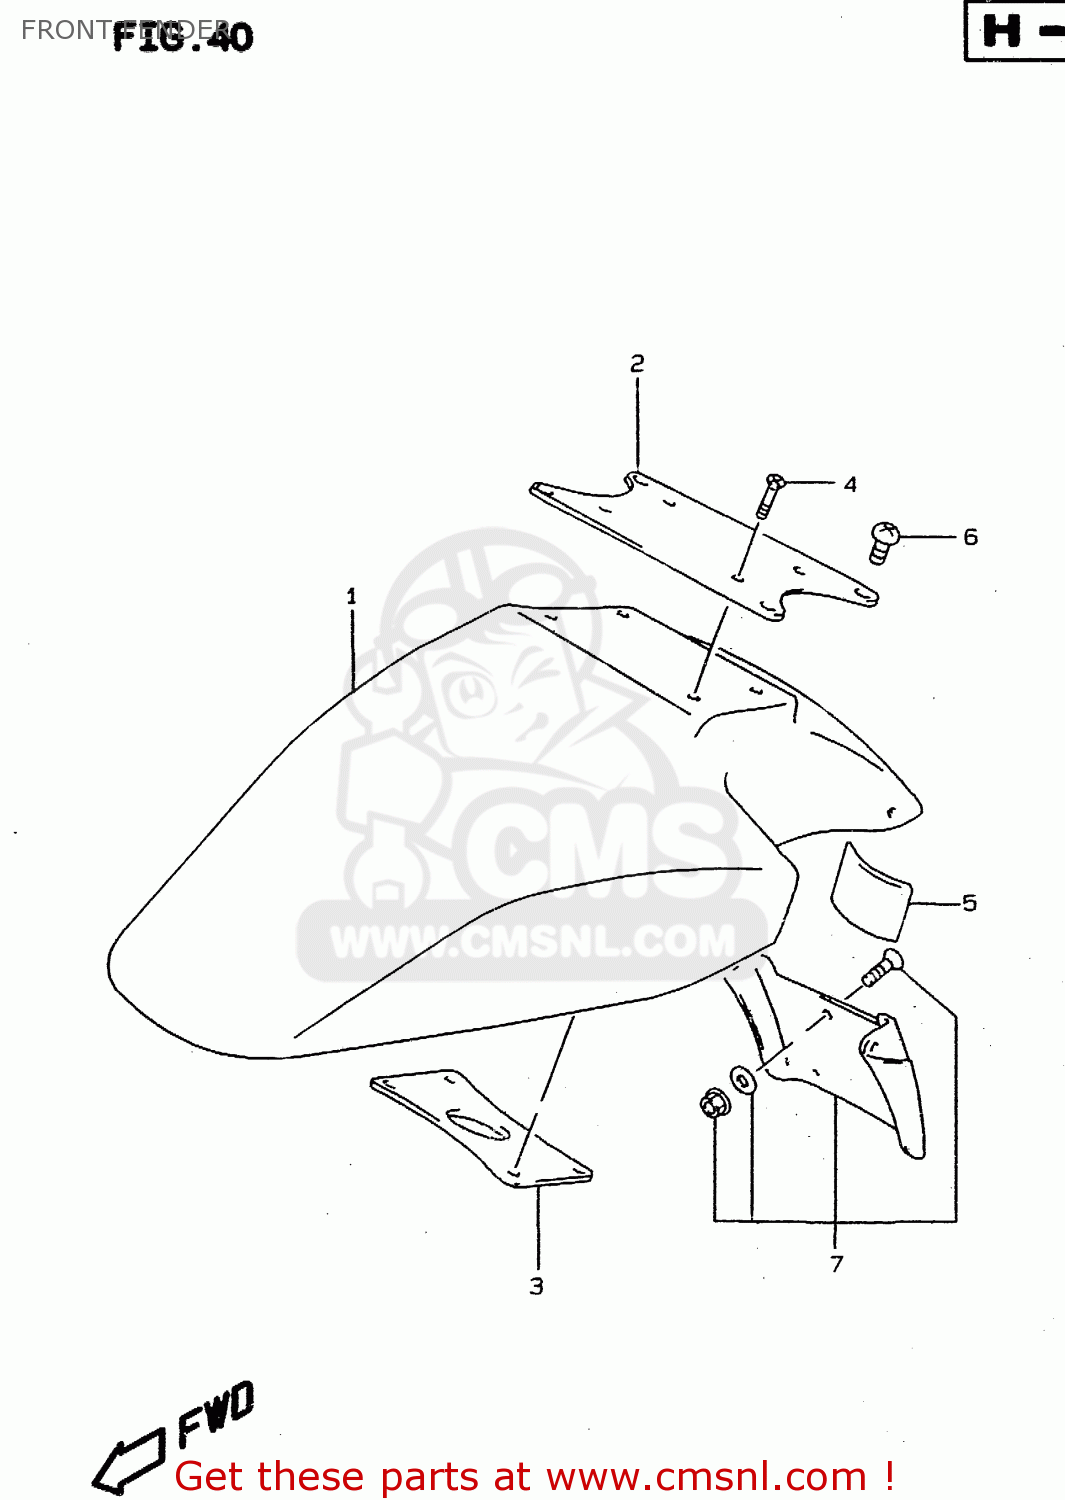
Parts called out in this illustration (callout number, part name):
1	FENDER,FR
2	BRACE,FR FENDER
3	BRACE,FR FENDER INNER
4	SCREW(5X18)
5	CUSHION,FR FENDER
6	SCREW(8X16)
7	MUDGUARD SET,FR FENDER
